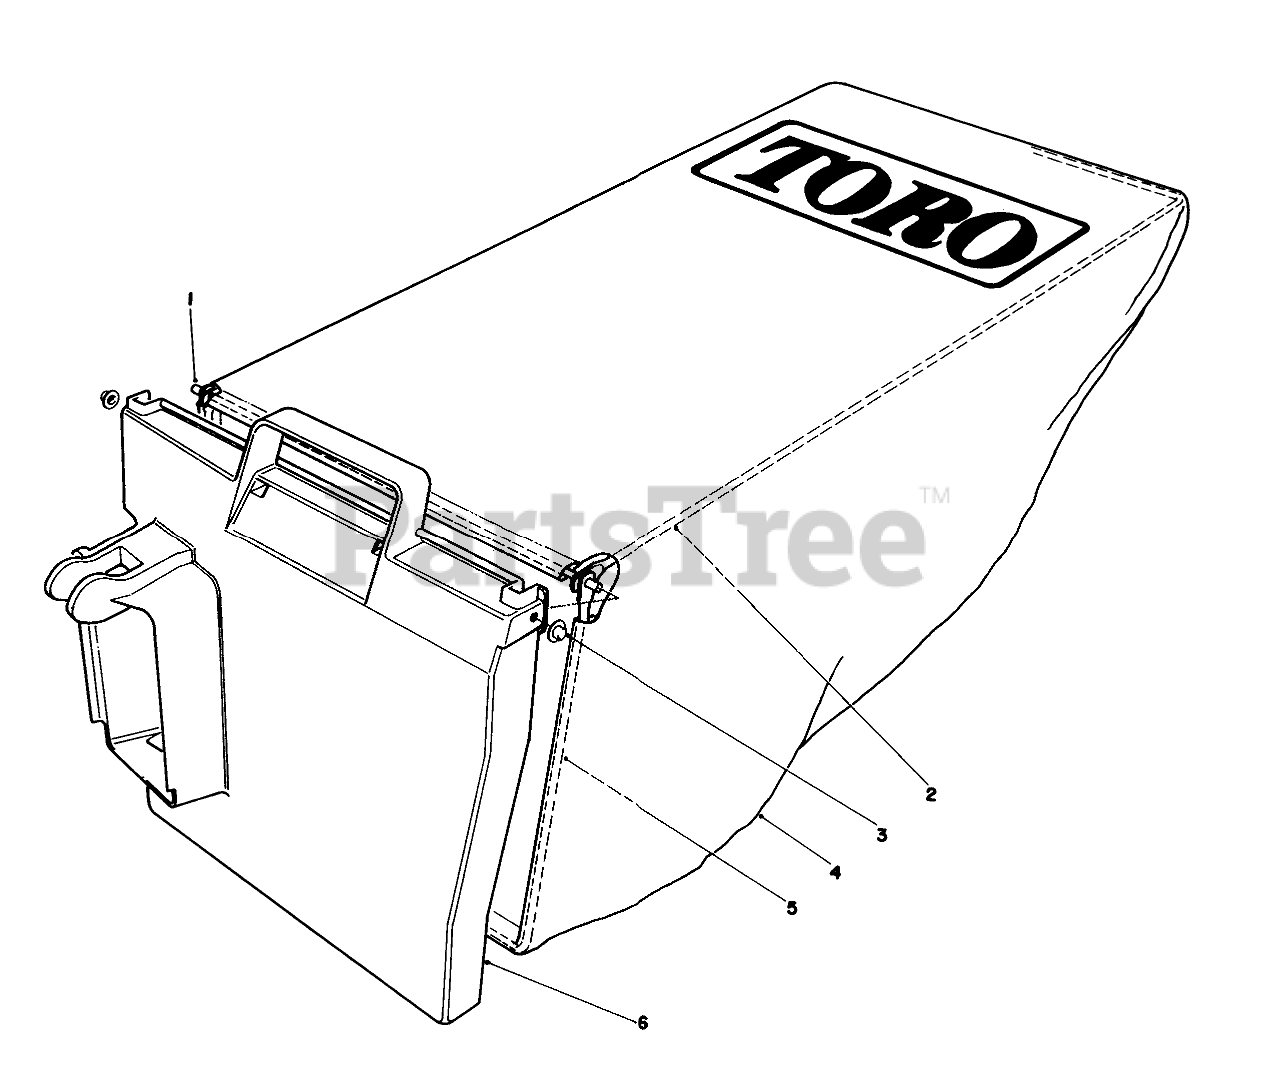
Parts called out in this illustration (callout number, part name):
1	HINGE PIN
2	BAG FRAME-UPPER
3	NUT-PUSH
4	Bag
5	Frame Bag
6	Door-Bag
